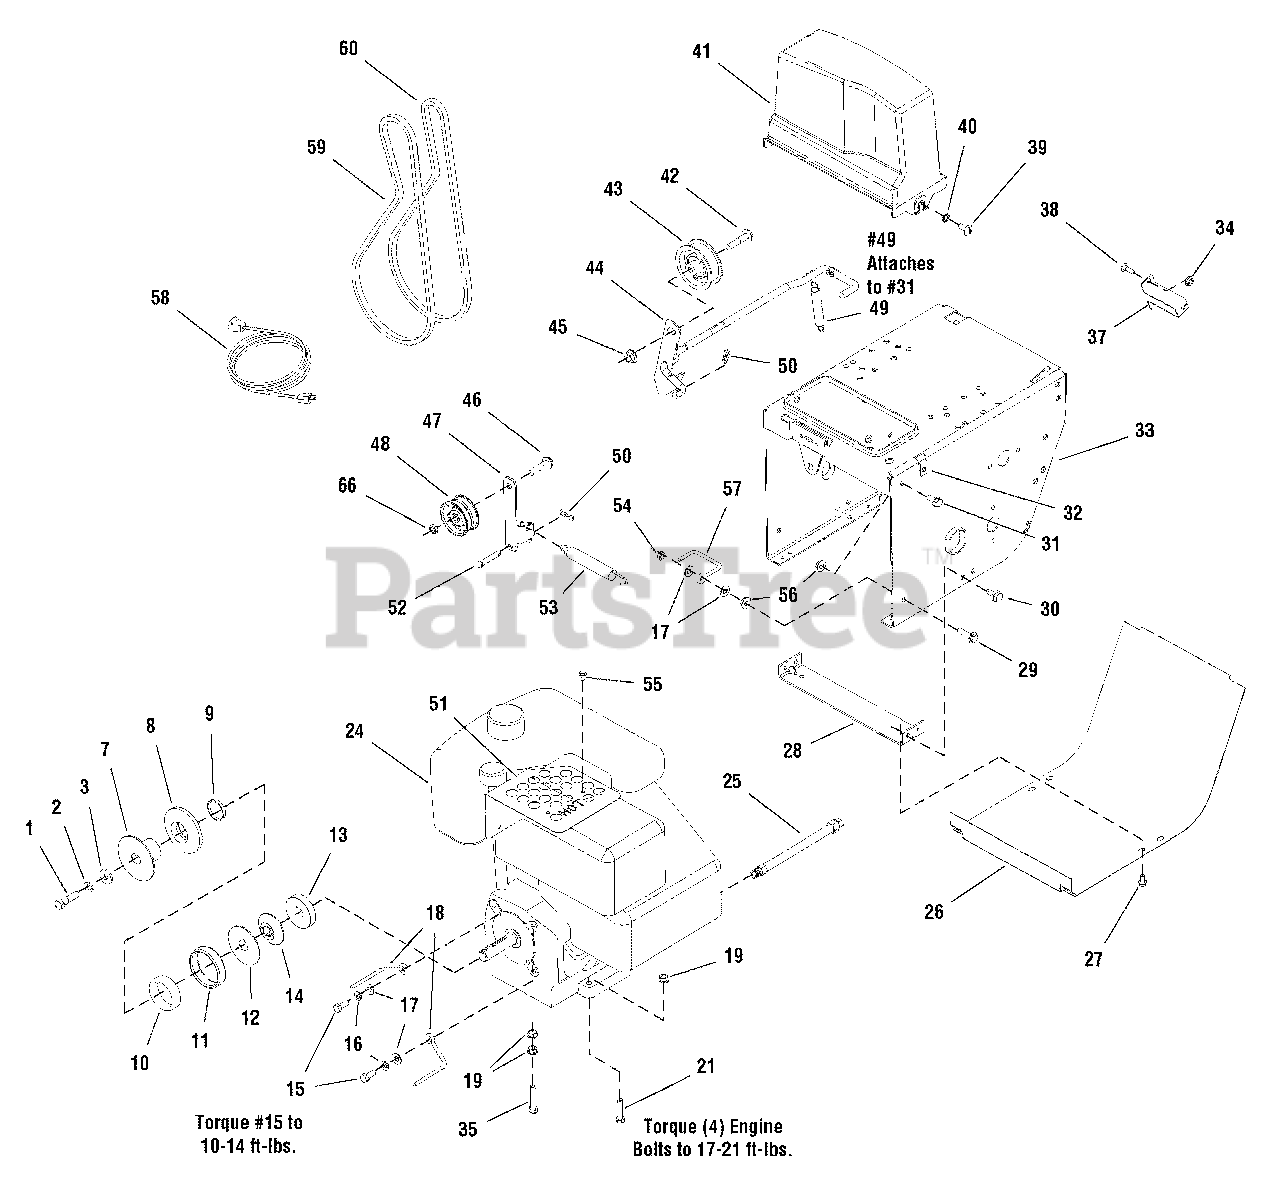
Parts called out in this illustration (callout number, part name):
1	CAPSCREW, Hex Head, 3/8-20 x 1-1/2, G8
2	LOCKWASHER, Spring, 3/8
3	WASHER, 3/8, 0.41ID x 1 OD x .13 Thick
7	PULLEY, Drive Half
8	PULLEY, Engine Half
9	WICK, Felt Oil, 4.65 Long .19 Wide
10	SPRING, Compression
11	SPRING, Compression
12	WASHER, Thrust, 0.766 ID x 2-3/4 OD x .06 Thick
13	PULLEY, Half, 2-1/4 OD 0.752 ID 0.64 Wide
14	PULLEY, Engine Outside
15	CAPSCREW, Hex Head, 5/16-24 x 3/4, G5
16	LOCKWASHER, Spring 5/16
17	WASHER, 5/16, 0.34 ID x 3/4 OD x .06 Thick
19	NUT, Hex Whiz Lock Flange, 5/16-18
21	CAPSCREW, Hex Head, 5/16-18 x 1-1/2, G5
25	HOSE, Oil Drain
26	COVER, Bottom Frame
27	SCREW, Hex Washer Head Taptite, 1/4-20 x 1/2
28	SUPPORT, Tie Bar
29	SCREW, Hex Whiz Lock Flange, 5/16-18 x 1-1/4
30	SCREW, Hex Washer Head Taptite, 5/16-18 x 3/4
31	SCREW, Hex Whiz Lock Flange, 5/16-18 x 3/4
32	NUT, Speed, 5/16-18 Lug Type 1/4 /.15
33	FRAME ASSEMBLY
34	NUT, Hex Keps, 1/4-20 Conical Washer
35	CAPSCREW, Hex Head, 5/16-18 x 1-3/4, G5
37	SUPPORT, Clutch Cable
38	CARRIAGE BOLT, 1/4-20 x 3/4
39	SCREW, Truss Head Slotted, 5/16-18 x 3/4
40	LOCKWASHER, External Tooth, 5/16
41	COVER, Belt
42	SCREW, Hex Whiz Lock Flange, 3/8-16 x 1-3/4
43	PULLEY, Idler, 2-3/4
44	ROD & ARM ASSEMBLY, Clutch/Brake
45	NUT, Hex Whiz Lock Flange, 3/8-16
46	SCREW, Hex Head, 3/8-16 x 1-1/2 .141 Thick
47	ARM, Idler 5-3/4 Long
48	PULLEY, Idler
49	SPRING, Extension
50	PIN, Quick
51	GUARD, Muffler
52	PIN, Flat
53	SPRING, Extension
54	NUT, Hex Centerlock 5/16-18
55	SCREW, Hex Washer Head Taptite, #10C x 1/2
56	NUT, Hex Whiz Lock Flange, 5/16-18
58	CORD, Electric Start
59	V-BELT 3L, Traction Drive
60	V-BELT HA, Auger Drive
66	NUT, Hex Toplock Jam, 3/8-16
